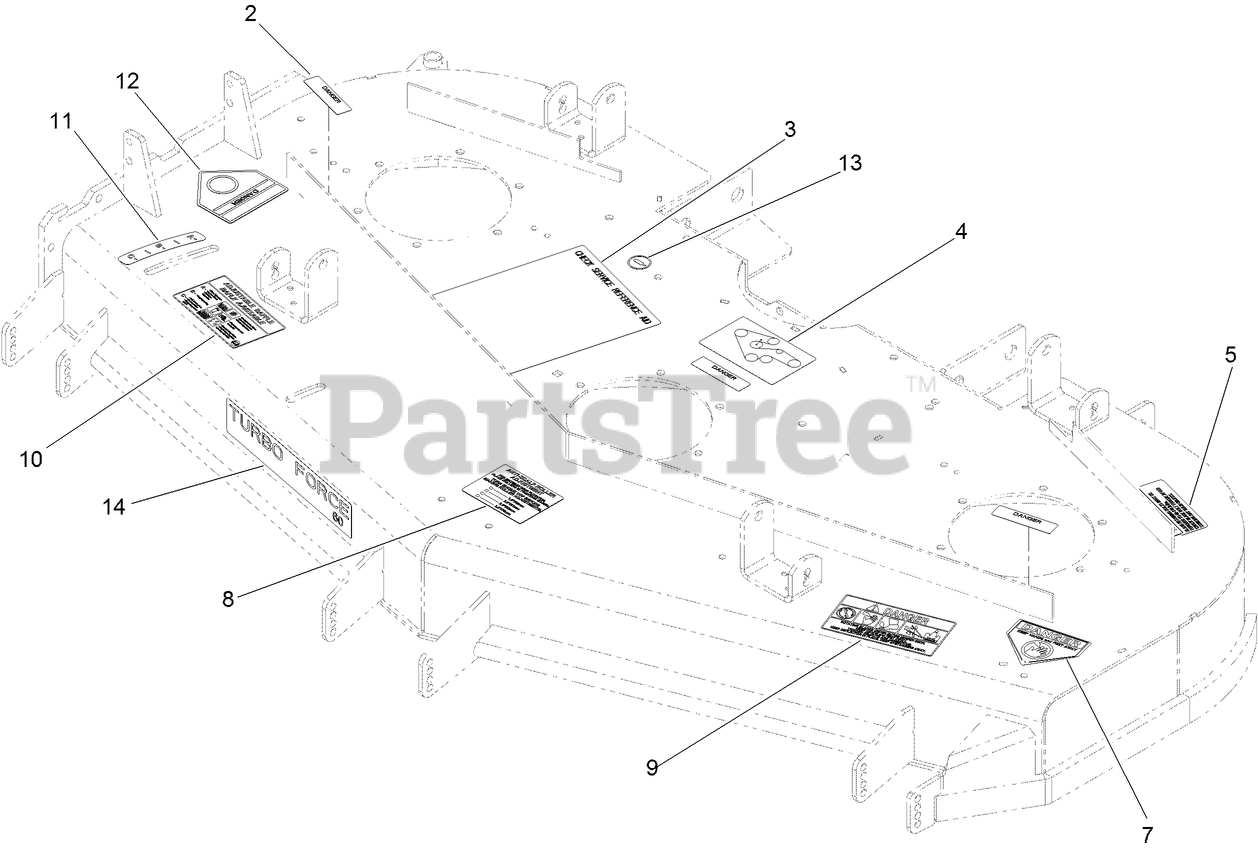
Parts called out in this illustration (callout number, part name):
2	DECAL-COVER, MISSING
3	DECAL-CHECK, SERVICE
4	DECAL-ROUTING, BELT
5	DECAL-TORQUE
7	DECAL-DANGER
8	DECAL-SCALP, ANTI
9	DECAL-DANGER, THROWN OBJECT
10	DECAL-ADJUSTMENT, BAFFLE
11	DECAL-SETTING, BAFFLE
12	DECAL-DANGER
13	DECAL-GREASE
